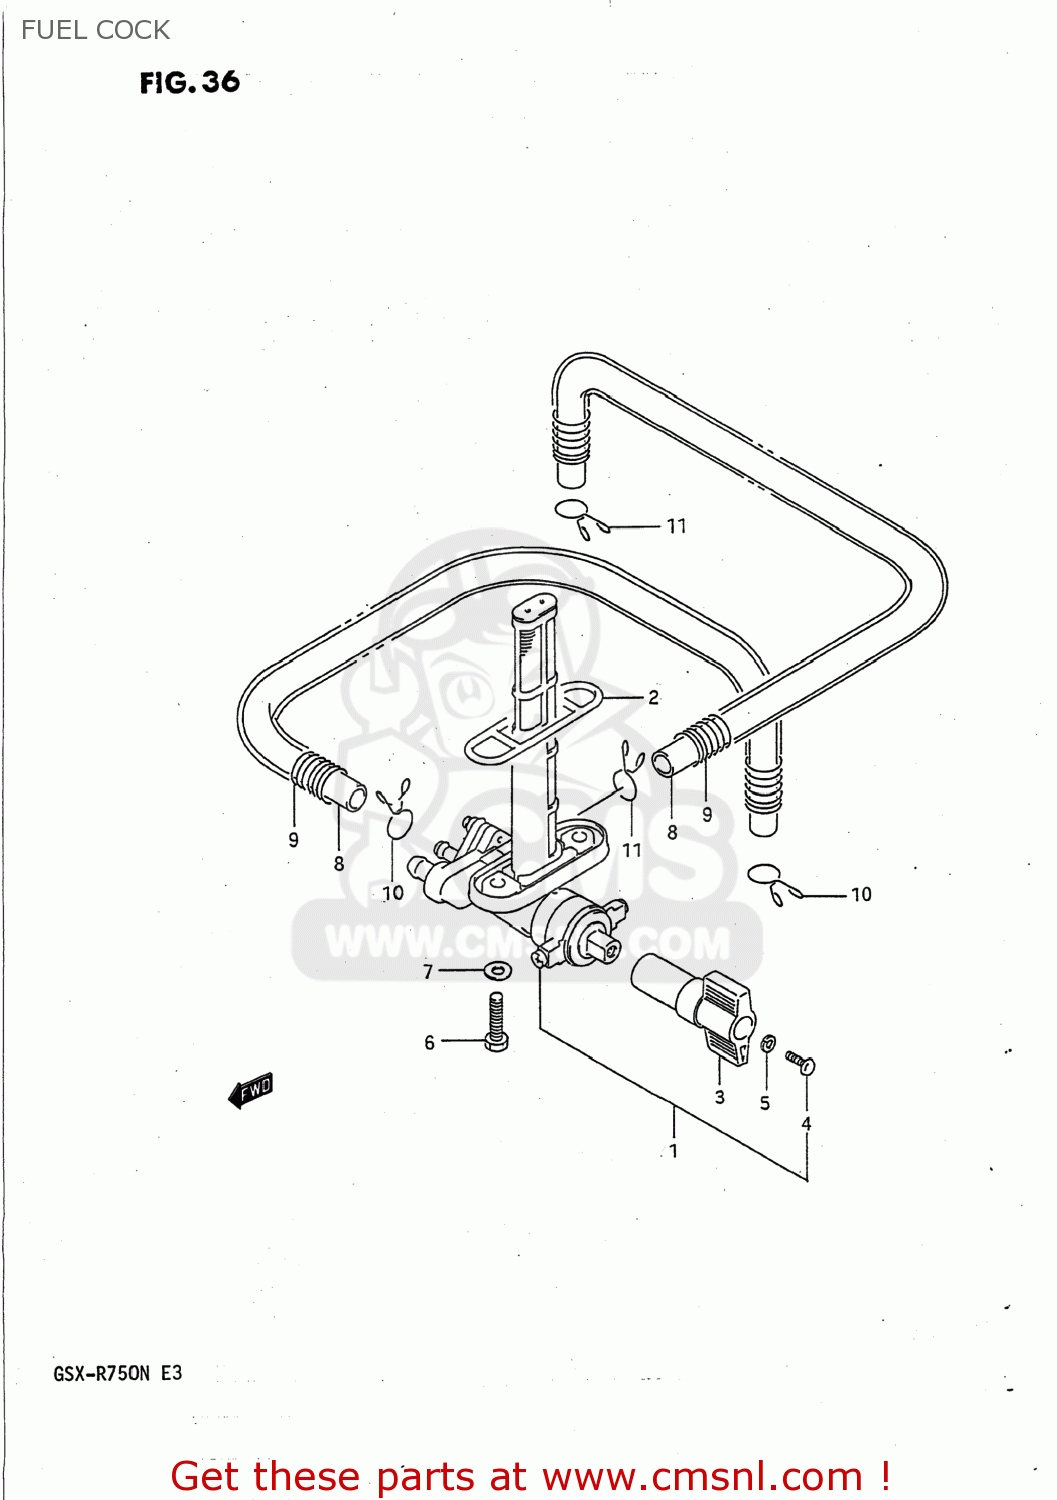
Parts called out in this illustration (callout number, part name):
1	COCK ASSEMBLY,FUEL
2	O RING,FUEL TANK JOINT
3	LEVER,FUEL COCK
4	SCREW
5	LOCK WASHER
6	BOLT(6X20)
7	GASKET(6.4X11.5X0.8) (NAS)
8	HOSE
9	SPRING
10	CLIP
11	CLIP
